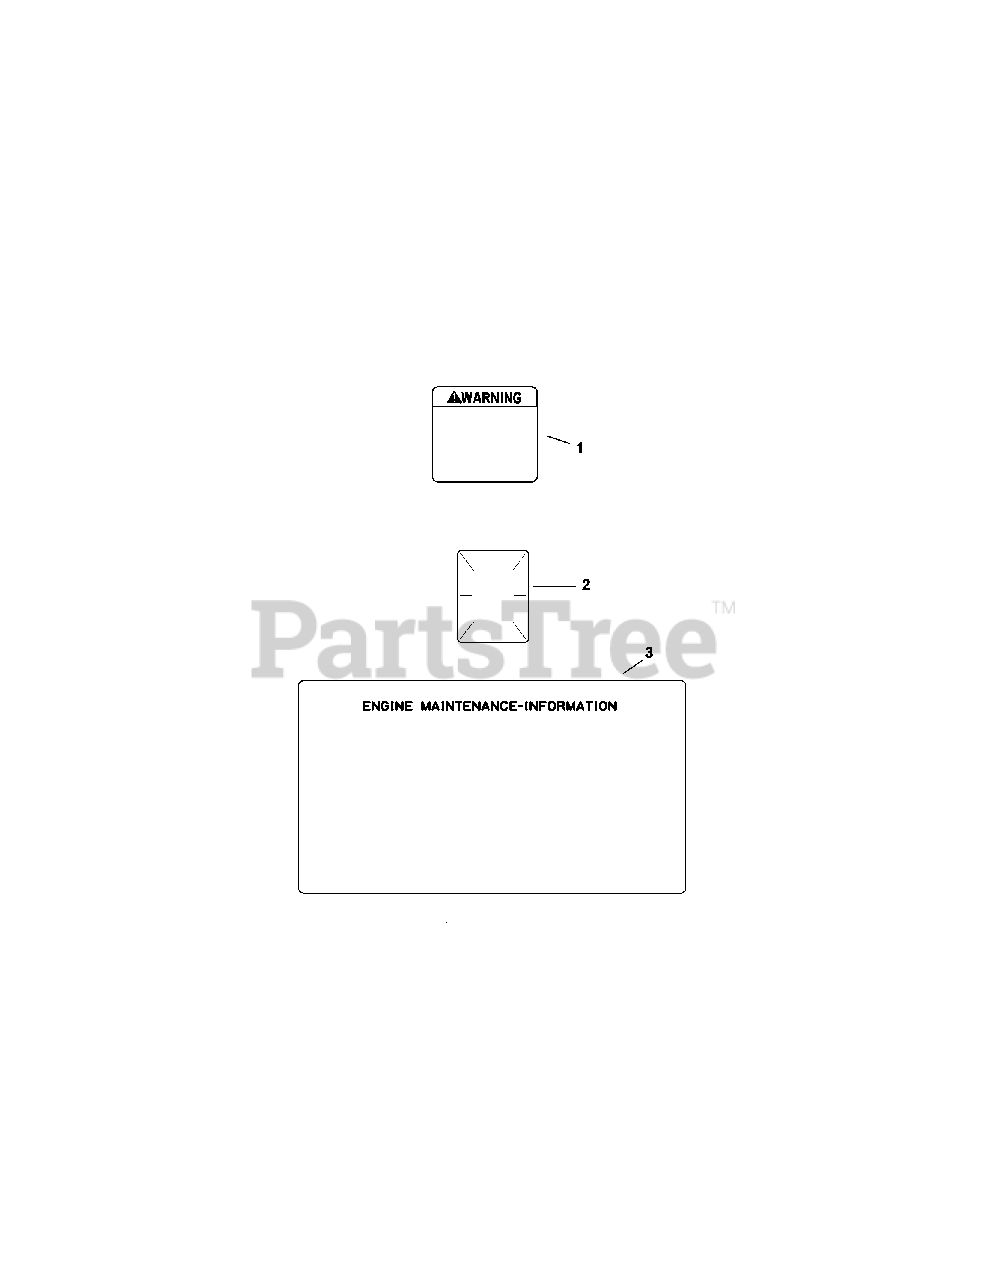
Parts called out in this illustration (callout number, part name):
1	Decal, Warning
2	Decal, Clear Laminate
3	Decal, Engine Maint.
